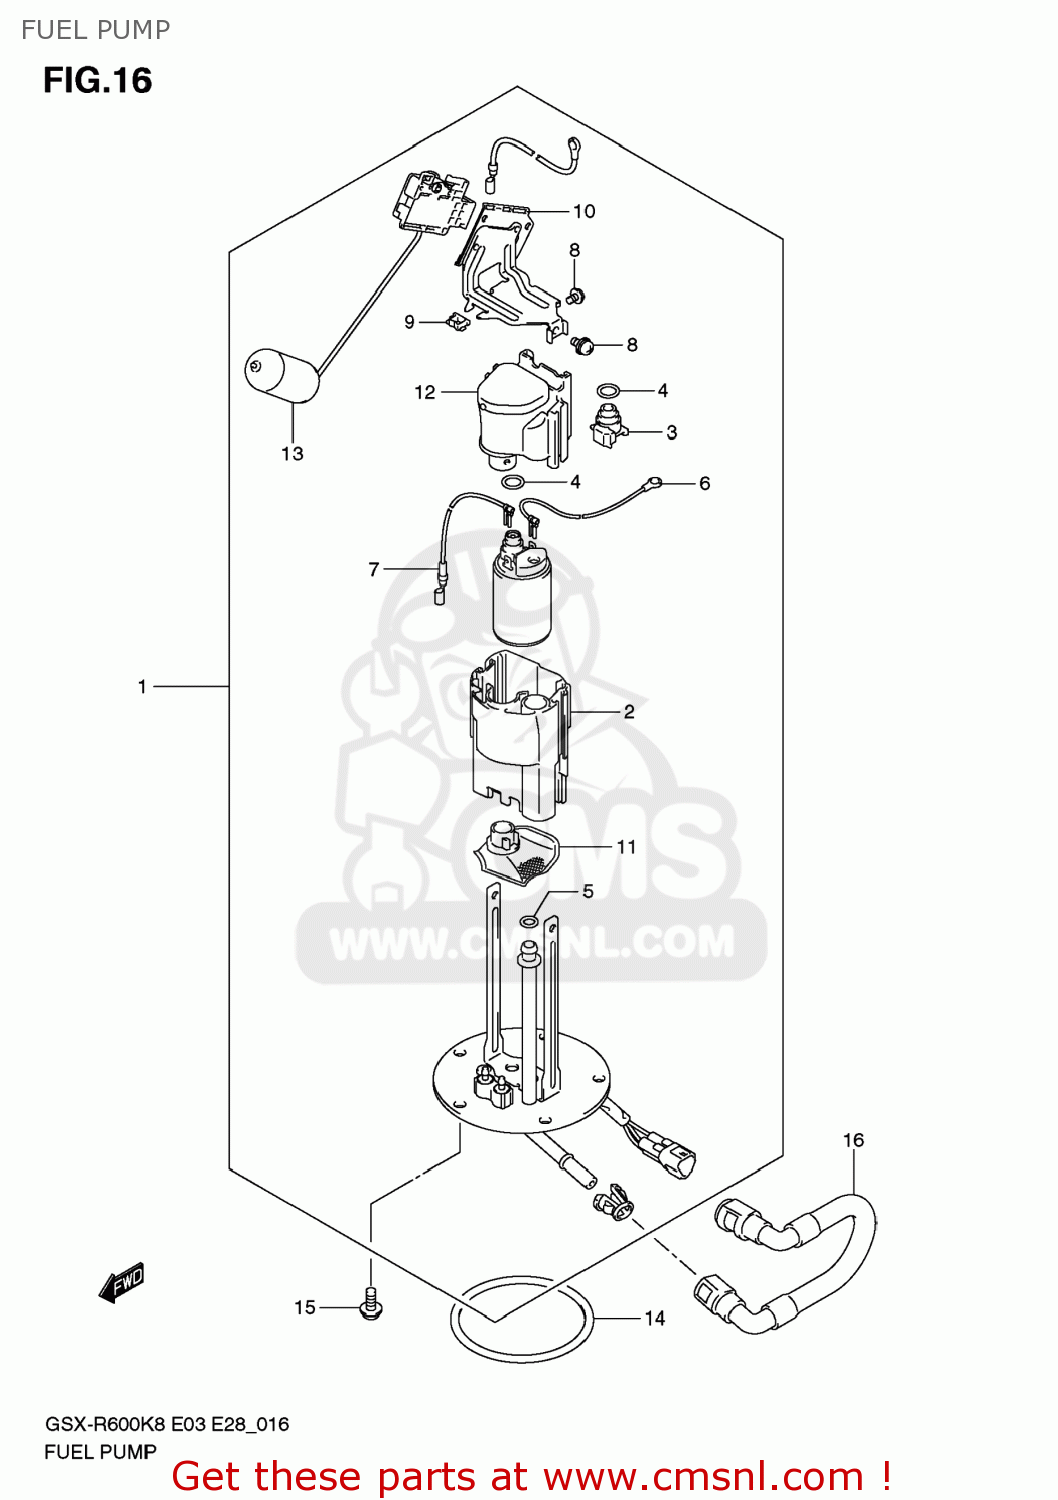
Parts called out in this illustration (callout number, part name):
1	PUMP ASSY,FUEL
2	CUP
3	JOINT
4	O RING
5	O RING
6	WIRE,EARTH
7	WIRE,LEAD
8	SCREW
9	SADDLE,EDGE
10	BRACKET,GAUGE
11	STRAINER
12	REGULATOR
13	GAUGE ASSY,FUEL LEVEL
14	O RING,FUEL PUMP
15	BOLT
16	HOSE,FUEL
